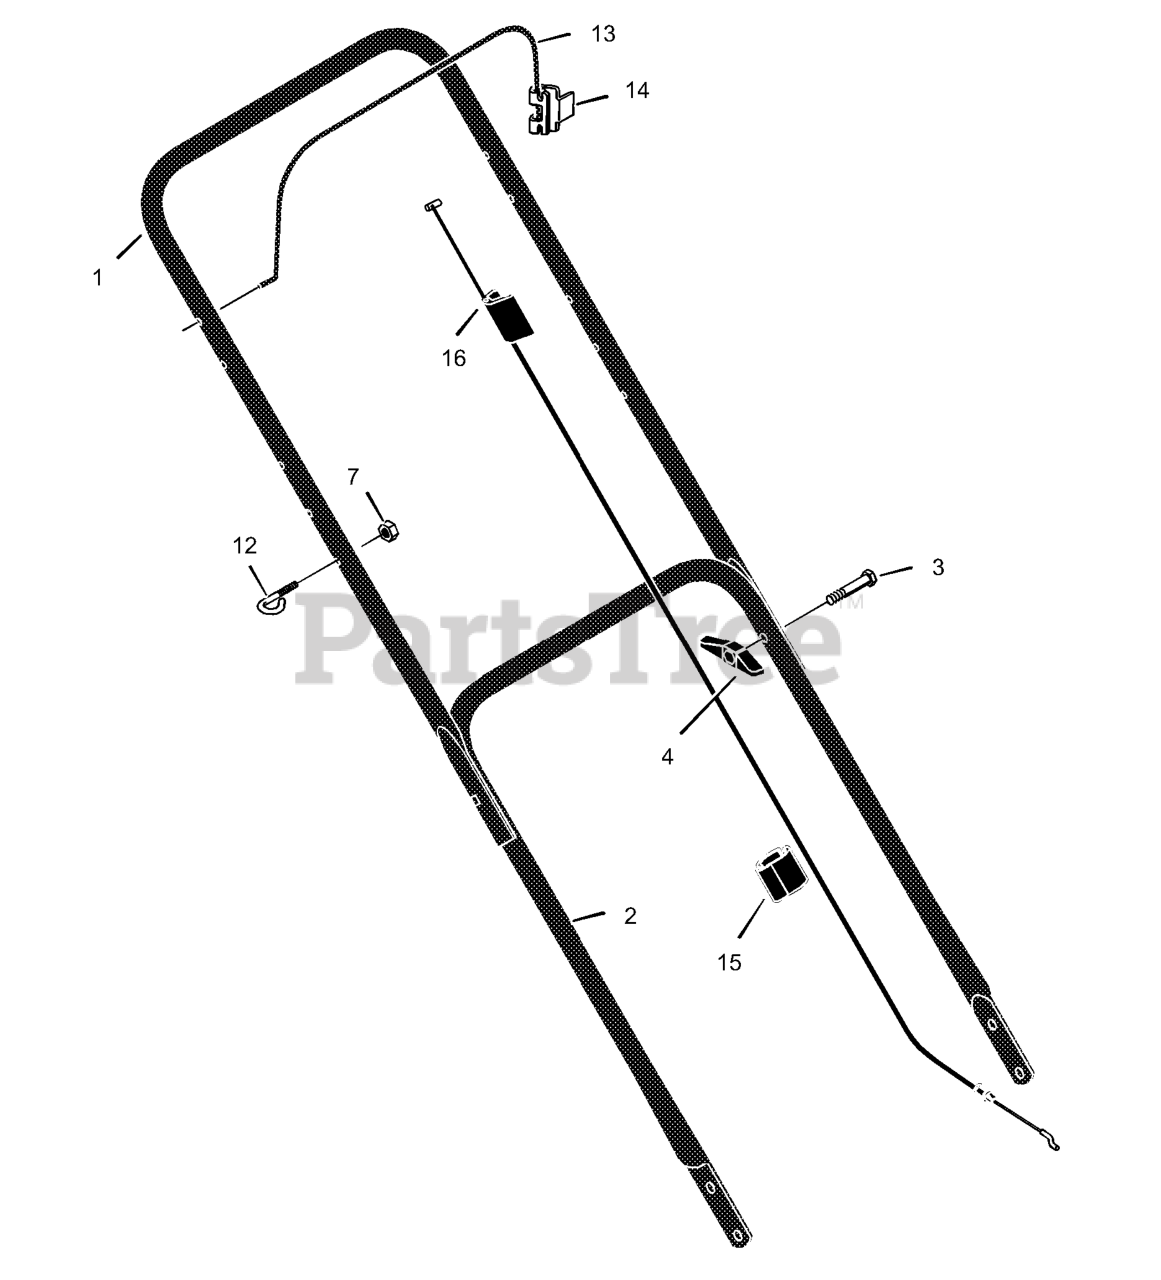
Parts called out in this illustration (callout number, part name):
1	Handle, Upper (Black)
2	Handle, Lower (Black)
4	Knob, Plastic
7	Locknut
12	Guide, Rope
13	Engine Stop Lever
14	Bracket, Stop Lever
15	Fastener, Double Cable
16	Engine Stop Cable
